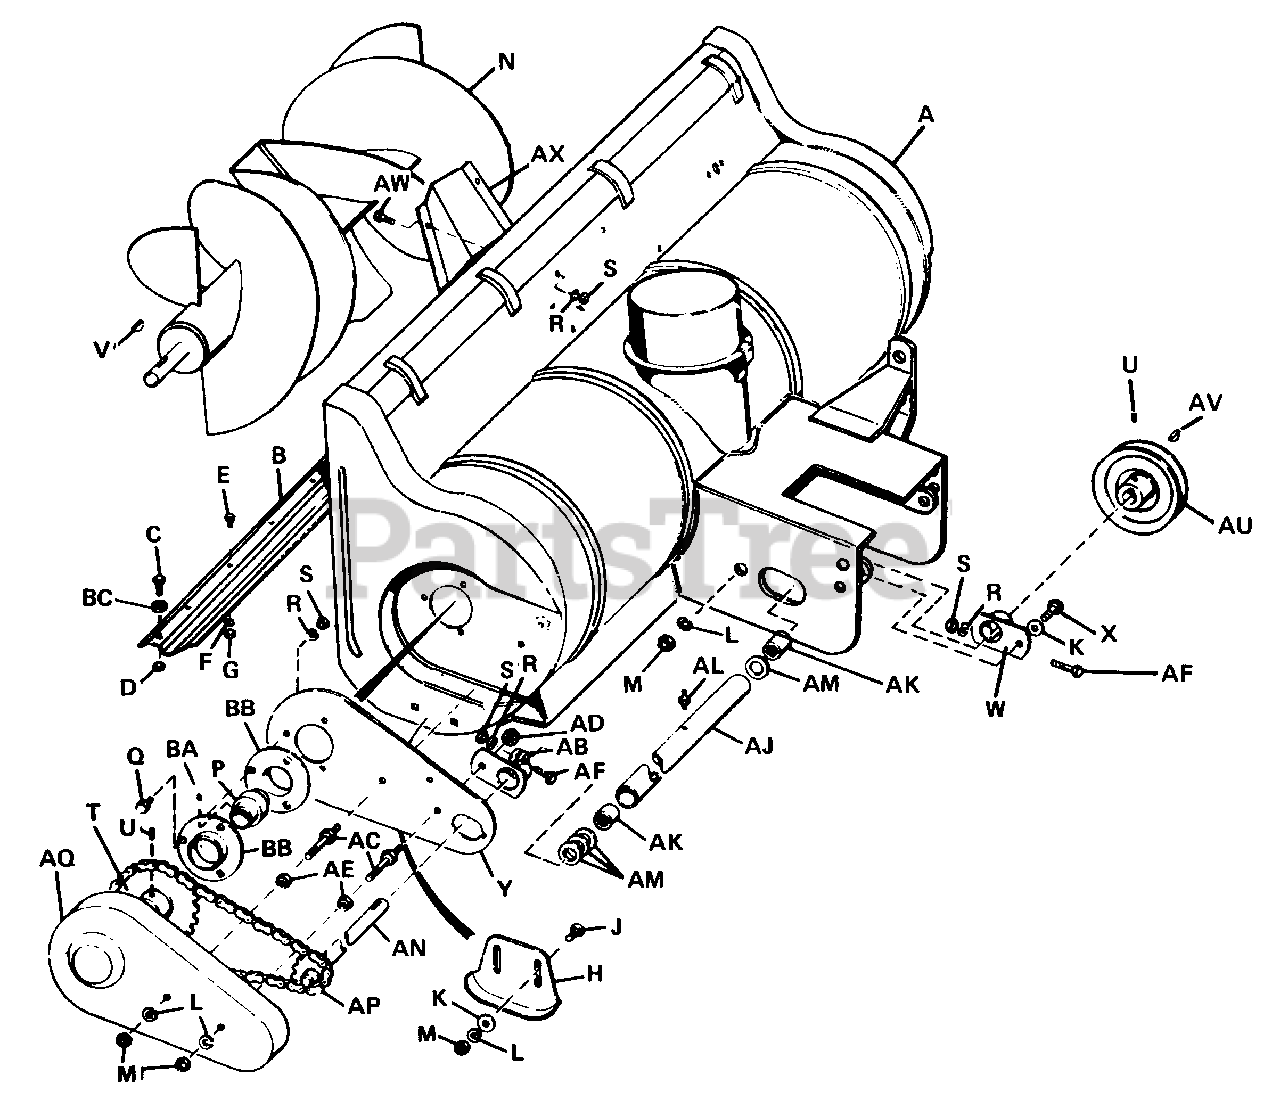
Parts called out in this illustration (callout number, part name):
A	Body Assembly
B	Body Scraper
C	Hex. Cap Screw, 5/16"-18 x 5/8"
D	Full Lock Hex. Nut, 5/16"-18
E	Hex. Cap Screw, 1/4"-20 x 5/8"
F	Lock Washer, 1/4"
G	Full Hex. Nut, 1/4"-20
J	Carriage Bolt, 3/8"-16 x 3/4"
K	Plain Washer, 3/8"
L	Lock Washer, 3/8"
M	Full Hex. Nut, 3/8"-16
N	Rotor Assembly
P	Bearing Cartridge w/713509 Set Screw
Q	Hex. Cap Screw, 5/16"-18 x 3/4"
R	Lock Washer, 5/16"
S	Full Hex. Nut, 5/16"-18
T	Rotor Sprocket
U	Set Screw, 5/16"-18 x 5/16"
W	Support Assembly Clamp
X	Hex. Cap Screw, 3/8"-1 x 1"
Y	Side Plate
AB	Support Assembly Clamp
AD	Nut, Flange, 3/8"-16
AE	Full Lock Hex. Nut, 3/8"-16
AF	Hex. Cap Screw, 5/16"-18 x 1-1/2"
AJ	Bearing Housing
AK	Needle Bearing
AL	Grease Fitting
AN	Shaft Assembly
AQ	Chain Guard
AV	Key, 3/16" Dia. x 3/4"
AW	Hex. Cap Screw, 5/16"-18 x 5/8"
BA	Set Screw, 1/4"-28 x 1/4" lg.
BB	Bearing Flange
